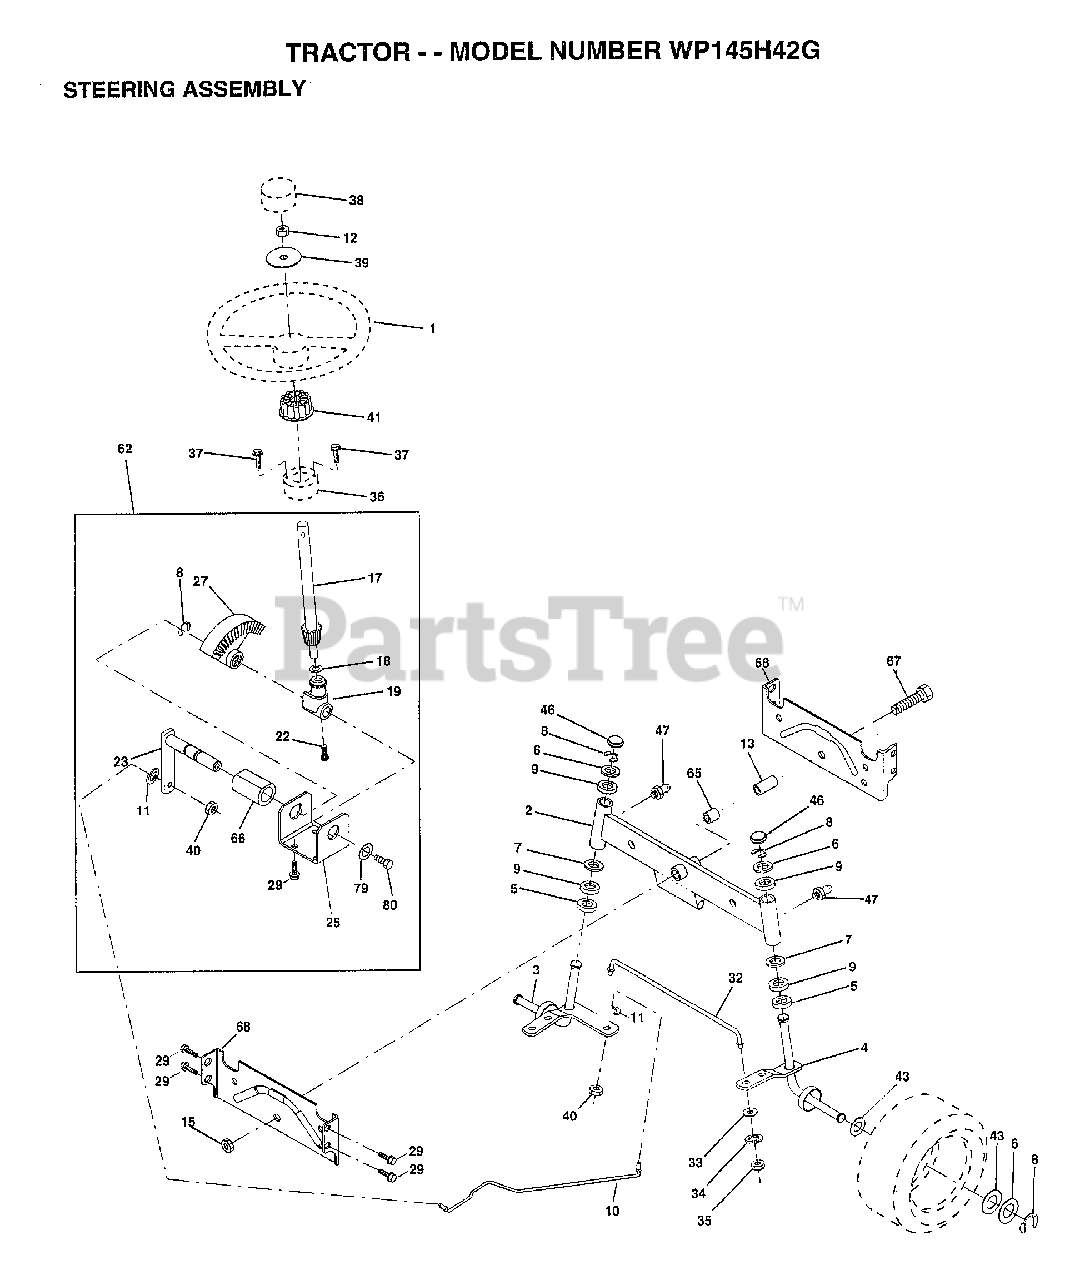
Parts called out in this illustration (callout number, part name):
2	AXLE ASM
3	SPINDLE.ASM.LH
4	"SPINDLE ASM,RH"
5	WASHER .T
6	WASHER
7	WASHER
8	RING
9	COL. SRTG. BEAR.
10	DRAGLINK-STAMPED
11	LOCKWASHER
13	BEARING AXLE
15	"NUT-LOC,FLANGE LT"
17	SHAFT ASM STEERNG
18	THRUST WASHER
19	SUPPORT.SHAFT.STEER
22	SCREW.HX.WSH.HD
23	SHAFT.ASM.PITMAN
25	BRKT-STEERING
27	GEAR SECTOR
29	SCREW
32	ROD.TIE.19.75
33	WASHER M
34	LOCKWASHER
35	NUT.LOCK.5/16-24
36	BUSHING.STRG.3/4
37	"SCREW-TT,10-32 FL"
38	"INSERT,STR WHEEL"
39	WASHER
40	GRIPCO NUT
41	ADAPTER LT
43	WASHER
46	CAP
47	ZERK M
62	KIT.STEER.ASM.LT
65	SPACER AXLE
66	"BEARING-ARM,PITMA"
67	BOLT
68	BRACE AXLE
79	WASHER
80	BOLT.HX.NYLON3/8-16X3/
